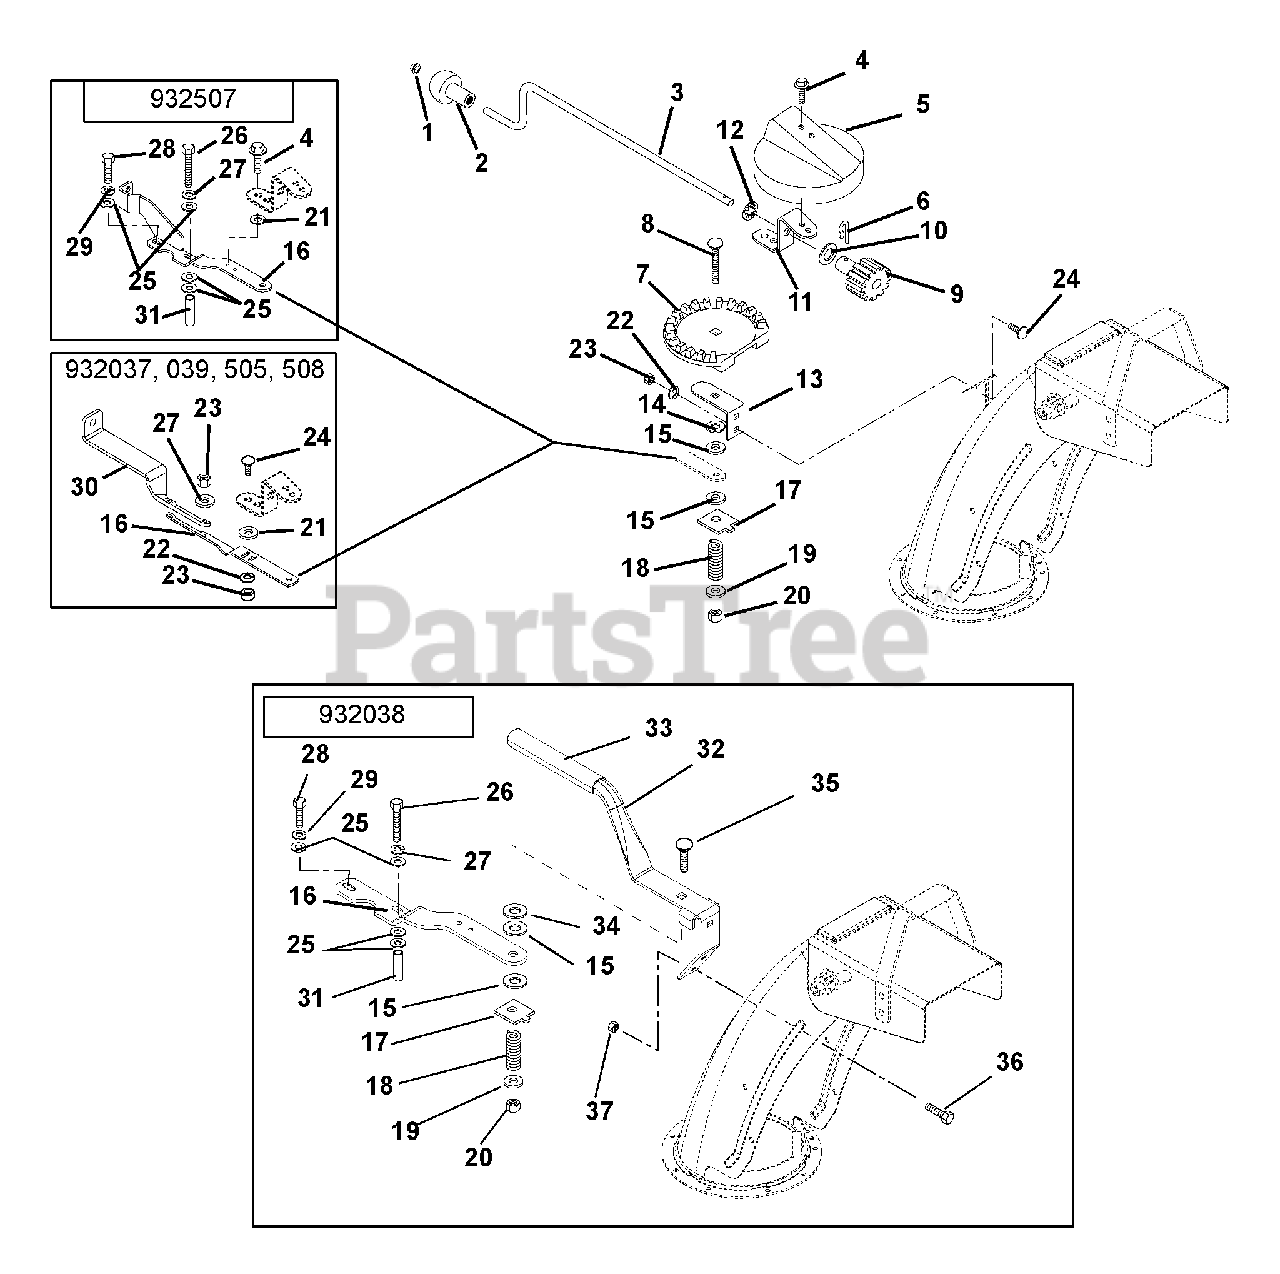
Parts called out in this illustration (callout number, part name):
1	CAP, 3/8 ROD YWZC
2	KNOB
3	CRANK, CHUTE
4	@SCR-TAP .25-20X.50 HWH TR YWZ
5	GEAR COVER
6	PIN, SPRING CLIP
7	CHUTE GEAR
8	@BLT-RDHDSQNK .38-16X2.50 G5YZ
9	PINION GEAR W/BRACKET
10	WSHR-FL-STL .630X1.005X.062 YZ
11	BRACKET-GEAR
12	PUSHNUT .625
13	GEAR STRAP
14	WSHR-FL-STL .380X1.50X.062 YWZ
15	FRICTION WASHER
16	BRACKET, CRANK SUPPORT
16	BRACKET, CHUTE SUPPORT
16	BRACE, CHUTE CONTROL
17	FRICTION PLATE
18	SG-COMP .187X.56X1.62
19	@WSHR-FL-STL.406X.812X.065 YWZ
20	@NUT-LK-CTR .38-16 YWZC
21	@WSHR-FL-STL.281X.62X.065 YWZC
22	@WSHR-LK .25X.062 REG YWZC
23	@NUT-HEX .25-20 YWZC
24	@BLT-RDHDSQNK .25-20X.75 G5YZ
25	WSHR-FL-STL .328X.875X.062YWZC
26	@BLT-HEX .25-20X1.50 GR5 YWZC
27	WSHR-LK .250X.077 HVY YWZC
28	@BLT-HEX .31-18X.75 GR5 YWZC
29	WSHR-LK .312X.097 HVY YWZC
30	SUPPORT, CHUTE CRANK
31	SPACER .280X.625X.640
32	CHUTE HANDLE, PAINTED
33	GRIP, CHUTE HANDLE, ORANGE
34	@WSHR-FL-STL.563X1.38X.109YWZC
35	@BLT-RDHDSQNK .38-16X2.25 G5YZ
36	@BLT-HEX .25-20X.50 GR5 YWZC
37	@NUT-LK-CTR .25-20 YWZC
